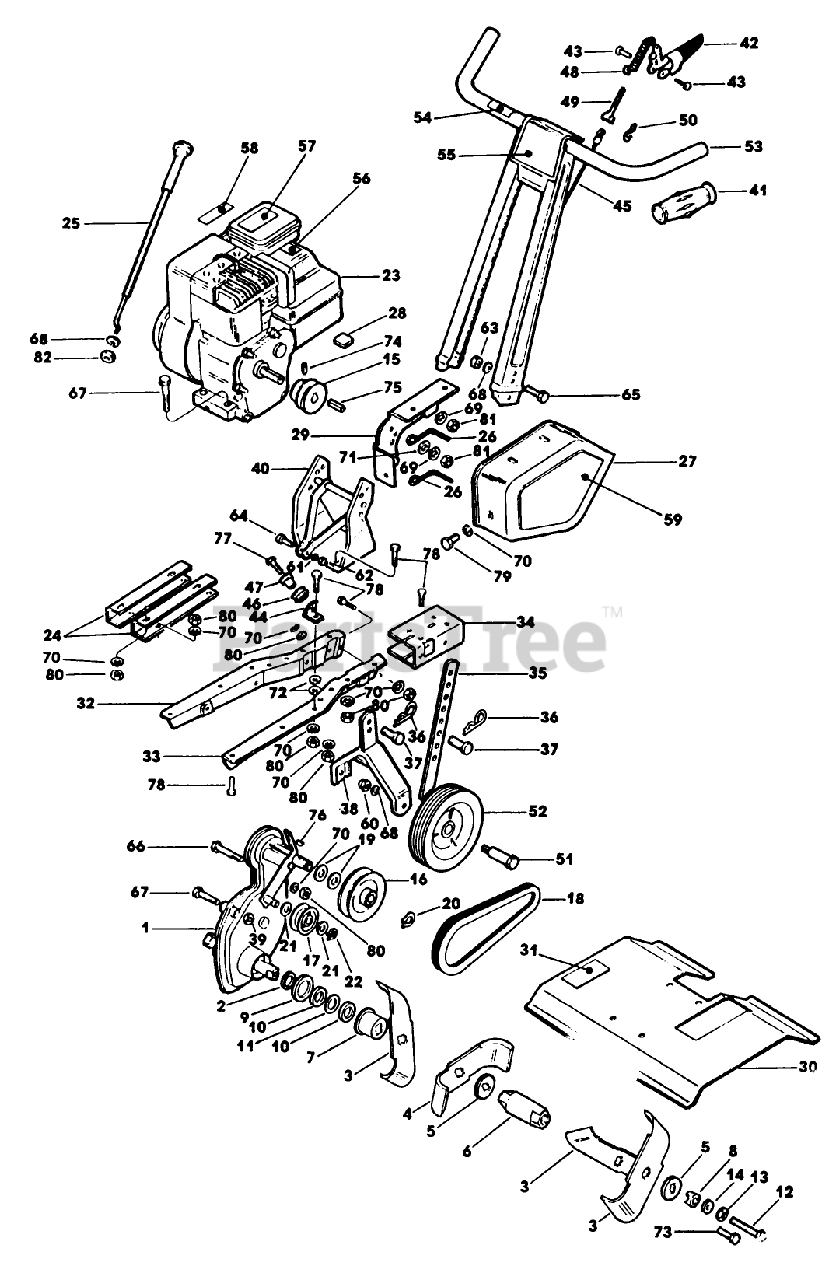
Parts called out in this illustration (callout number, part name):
2	SEAL
9	SEAL-FELT
10	SEAL
11	WASHER
12	BOLT
21	WASHER
36	PIN - SPRING CLIP
60	NUT-LOCKING
62	NUT E
63	NUT
68	WASHER
74	SET SCREW
78	SCREW - HEX
80	NUT SS
81	NUT
